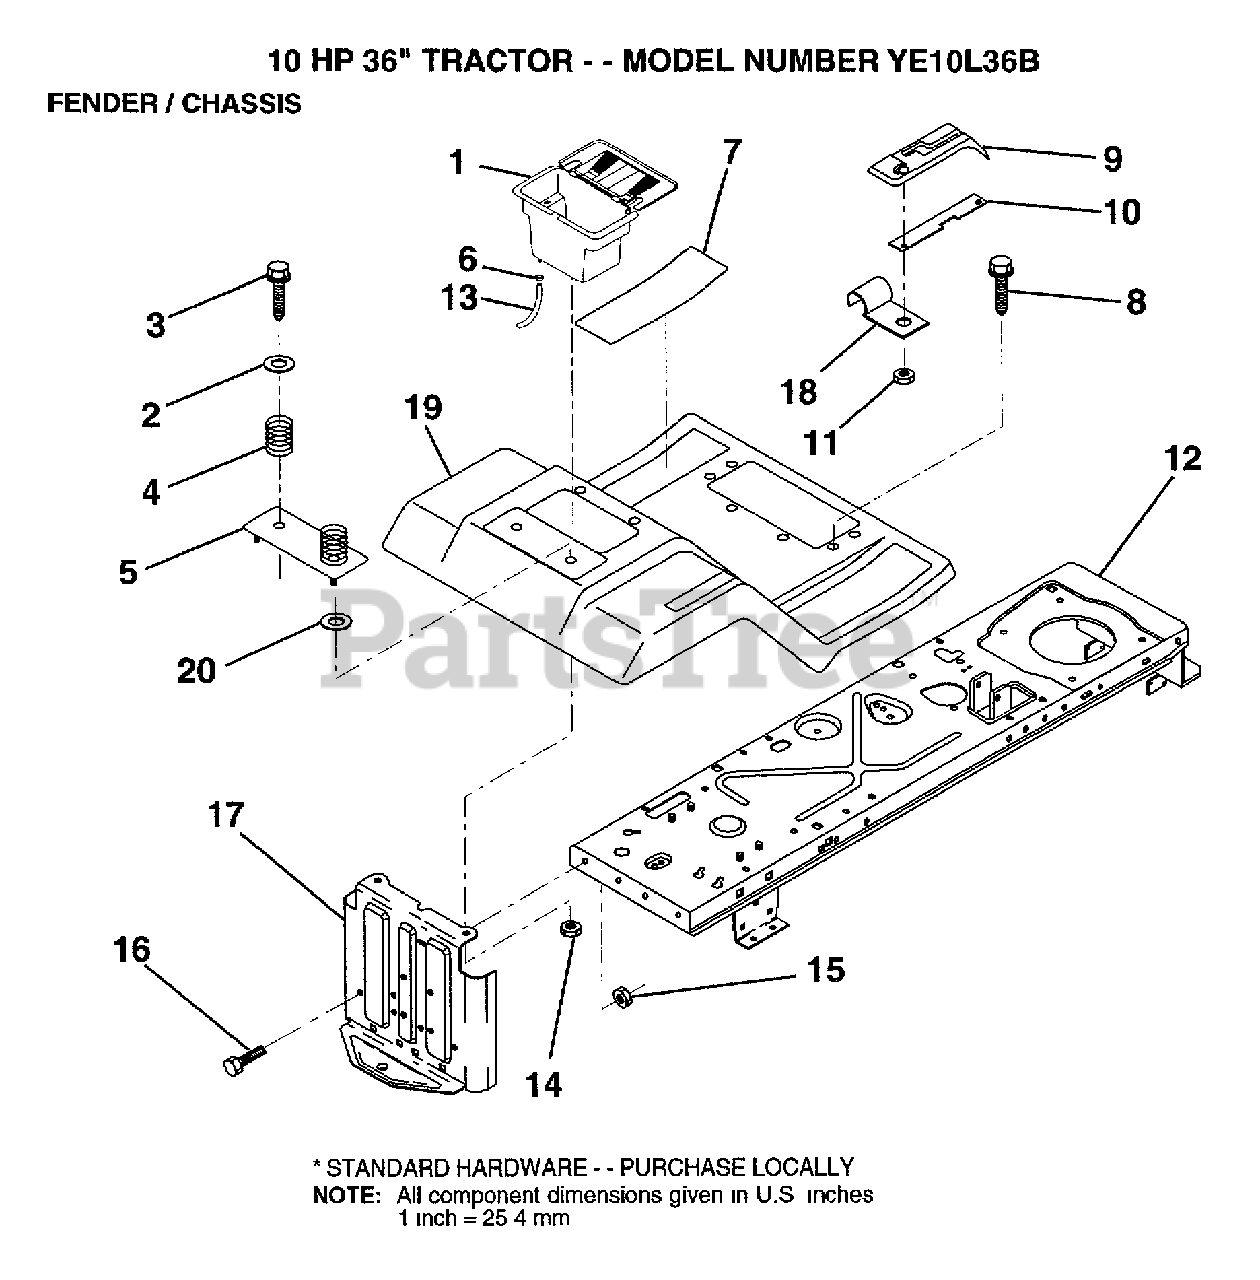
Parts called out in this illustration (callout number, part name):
2	WASHER
3	SCREW
4	SPRING COMPRESSIO
5	BTRY FENDER PLATE
6	HOSE CLAMP T
7	PAD FOOTREST
8	SCREW
9	CONSOLE SHFT 4SP
11	NUT
14	NUT
16	BOLT
17	DRAWBAR
18	"CLIP,INSULATOR"
